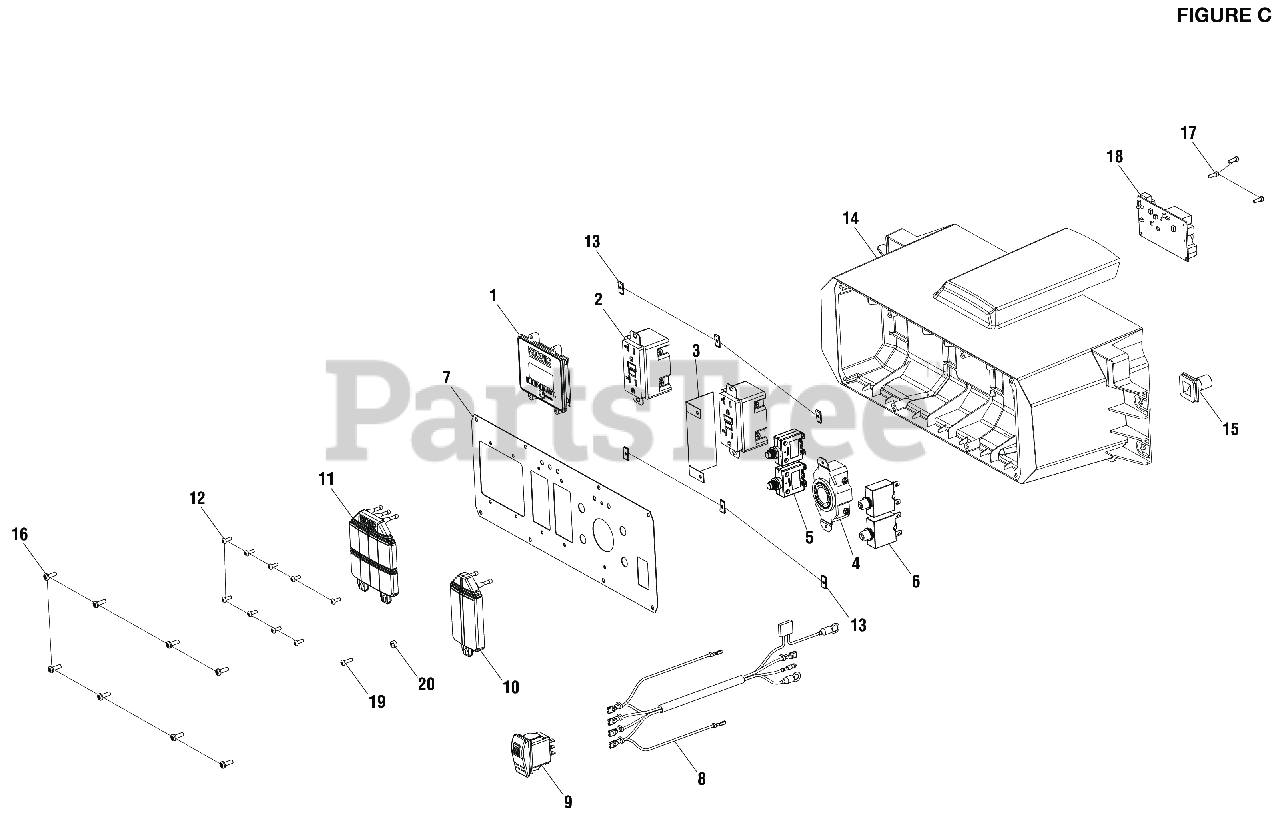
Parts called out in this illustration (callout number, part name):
1	GENSMART DISPLAY, 120/240V
2	Duplex GFCI Receptacle (120 Volt)
3	INSULATOR
4	Twist Lock Receptacle (120/240 Volt, 30 Amp, L14-30R)
5	Circuit Breaker (20 Amp, 125 Volt)
6	Circuit Breaker (30 Amp)
7	ELECTRICAL FACEPLATE, RD907500P
8	E-START WIRE HARNESS RD907500P
9	Start Switch w/Lock
10	RAIN SHIELD, 30 AMP TWISTLOCK
11	RAIN SHIELD, DUEL GFCI
12	Screw (#6-20 x 3/8 in., T15 Torx Pan Hd.)
13	NUT, SPEED #6-18
14	WRAPPER BOX, RIDGID
15	Rubber Boot (Control Panel Assembly)
16	Screw (#8-18 x 1/2 in., T20 Torx Pan Hd.)
17	Screw (6-20 x 3/8 in., Phillips Pan Hd.)
18	Circuit Board Assembly
19	SCREW, #6-10 X 0.5 TYPE B ZINC TORX HD
20	SPACER 4mm
